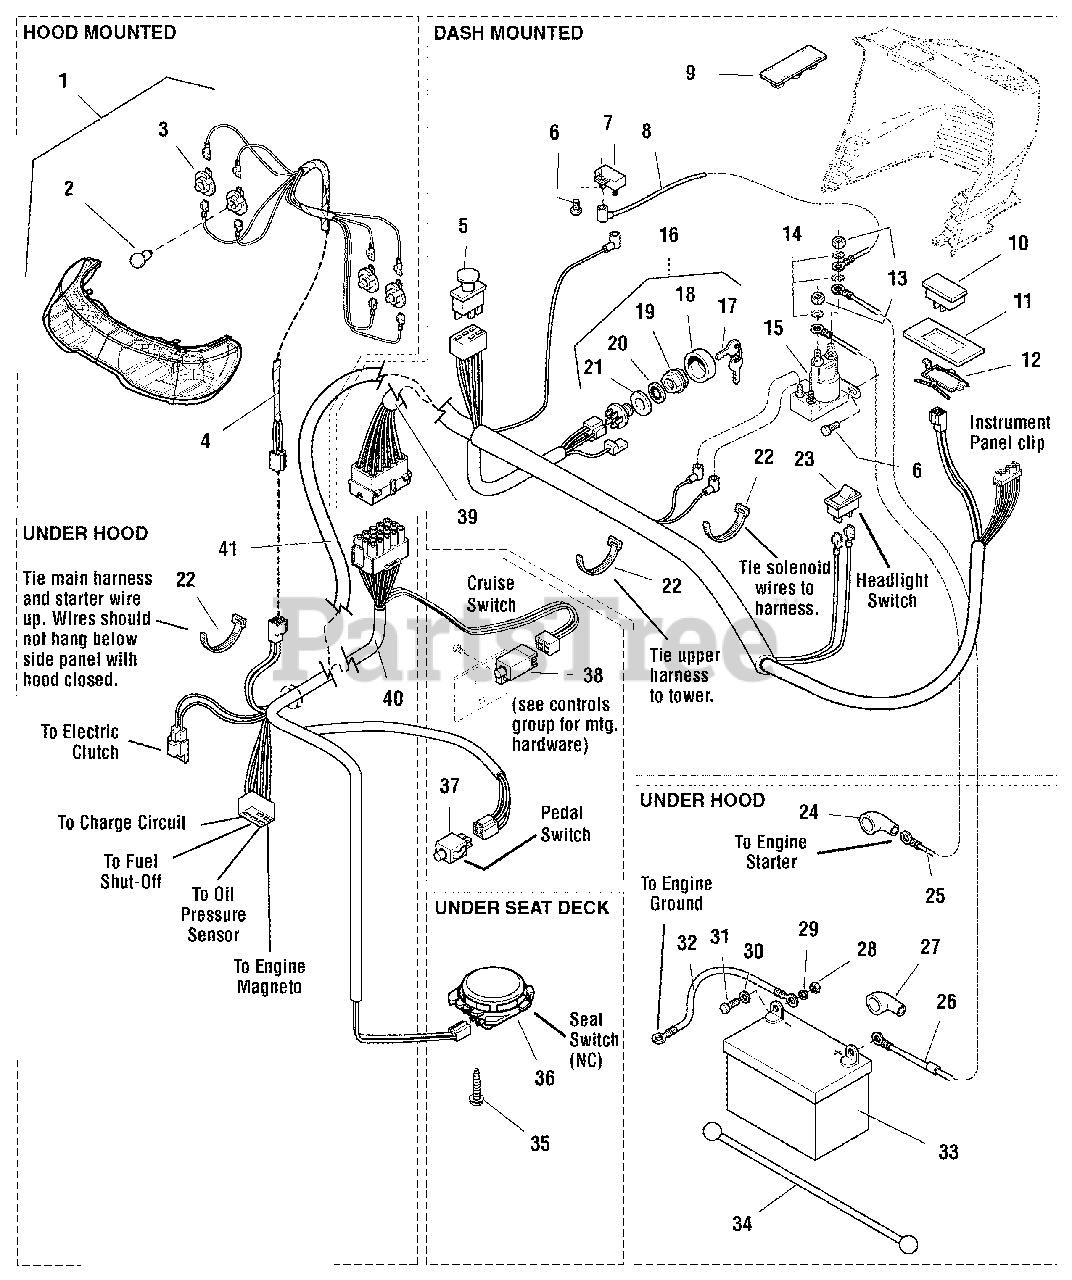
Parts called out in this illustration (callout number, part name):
1	HEADLIGHT ASSEMBLY, 4 Bulb, (Includes Ref. Nos. 2 & 3)
2	BULB, Headlight, 12.8V
3	SOCKET ASSEMBLY, Headlight, Sealed
4	HARNESS, Headlight
5	SWITCH, PTO Push/Pull Symbols
6	CAPSCREW, Hex Washer Head Taptite, 1/4-20 x 1/2, Black
7	BREAKER, Circuit, 12 Volt 20 Amps
8	WIRE, 12GA 5-15/16 Long, Red
9	PLUG, Hole, Square
10	HOUR METER, (Includes Ref. Nos. 12)
12	CLIP, Hour Meter (Service Only)
13	NUT, Hex, 5/16-24
14	LOCKWASHER, External Tooth, 5/16
16	SWITCH ASSEMBLY, Ignition, 6 Pin, (Includes Ref. Nos. 17, 18, 19, 20 & 21)
17	KEYS, Set of 2
18	COVER, For Ignition Switch, Plastic
19	NUT, Hex Flange, 5/8-32, Ignition Switch
20	LOCKWASHER, Internal Tooth, 5/8, Thin
21	WASHER, Shim
22	TIE, Strap, 7-5/16 Long
23	SWITCH, Headlights , 2 Terminal
24	BOOT, Insulator Cable Terminal, 1-15/16 Long, Red
25	CABLE, #6 x 25" Long, Ring Terminals
26	CABLE, #6 x 8" Long, Ring Terminals
27	BOOT, Insulator Battery Terminal
28	NUT, Hex, 1/4-20
29	LOCKWASHER, 1/4
30	WASHER, 1/4
31	CAPSCREW, Hex Head, 1/4-20 x 3/4
32	CABLE, #6 x 26 Long, Ring Terminal
33	BATTERY, 12 Volt
34	STRAP, Battery, 14 Long, Rubber
35	CAPSCREW, Hex Washer Head Plastite, 1/4 x 1/2
36	SWITCH, Seat, Grey, NC
37	SWITCH, Push Button, Foot Pedal
38	SWITCH, Cruise Control, Grey, NO
39	HARNESS, Wiring Upper (Units with 2 Piece Harnes)
40	HARNESS, Wiring Lower (Units with 2 Piece Harness)
41	HARNESS, Wiring, (Units with 1 Piece Harness)
